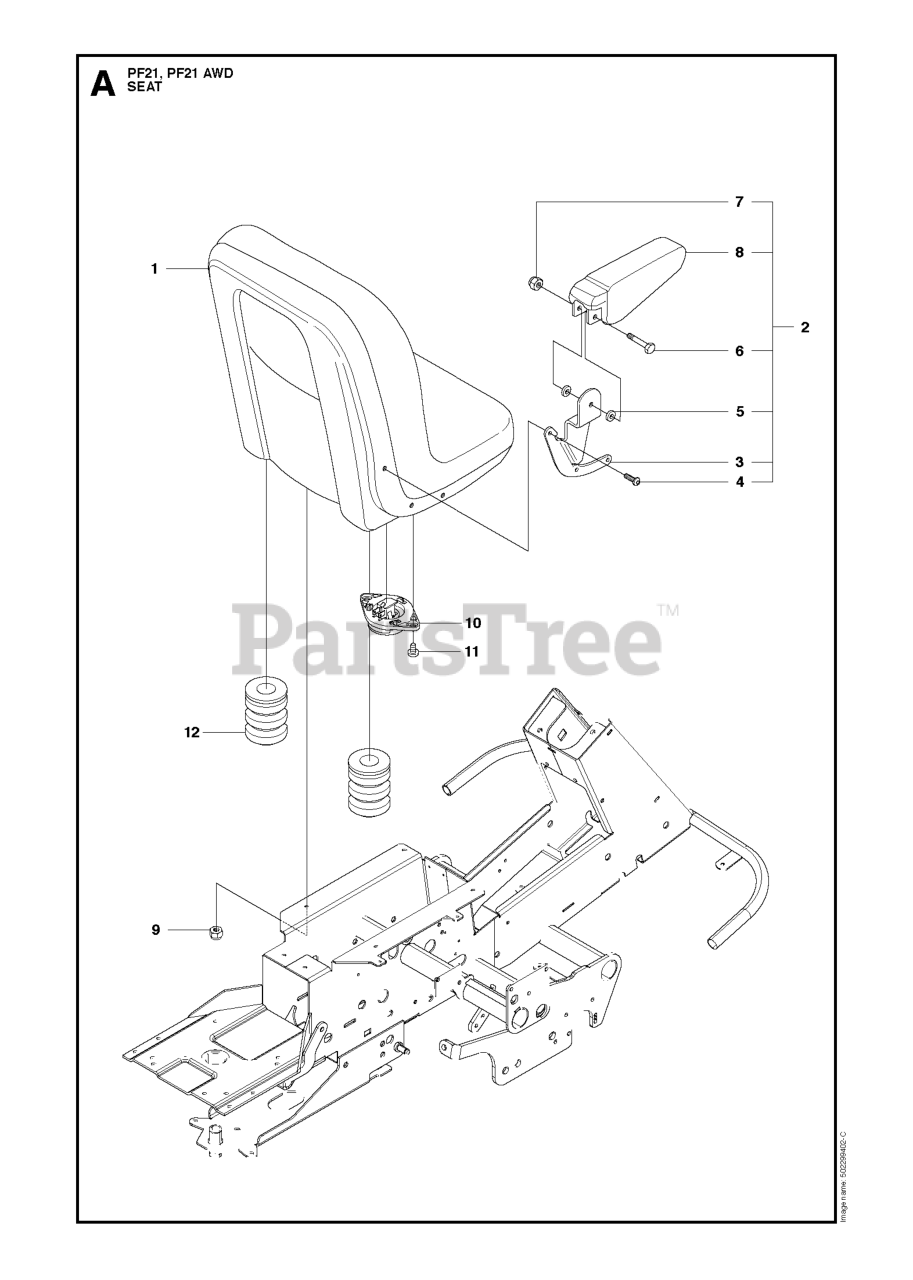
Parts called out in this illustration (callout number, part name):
9	LOCKNUT M8
10	ANTI-START SWITCH CPL
11	SCREW
